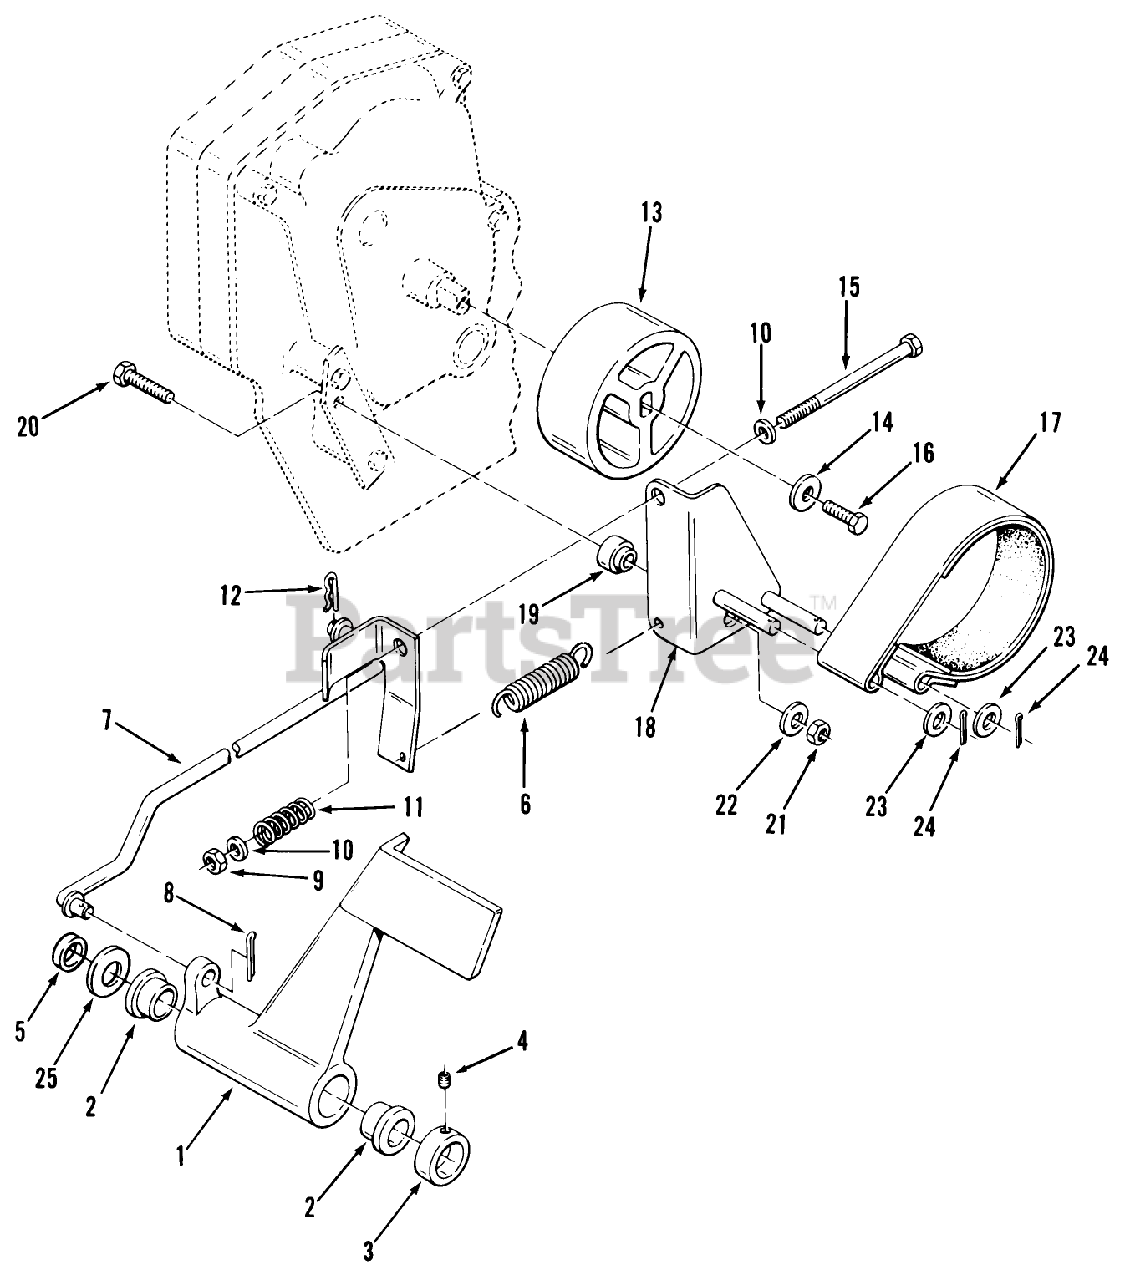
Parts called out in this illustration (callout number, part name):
1	PEDAL *R
2	BUSHING
5	Spacer 312-A Only
6	SPRING
11	SPRING-COMPRESSION
12	Hairpin
13	DRUM-BRAKE
14	WASHER
17	ASSY-BRAKE BAND
25	WASHER
